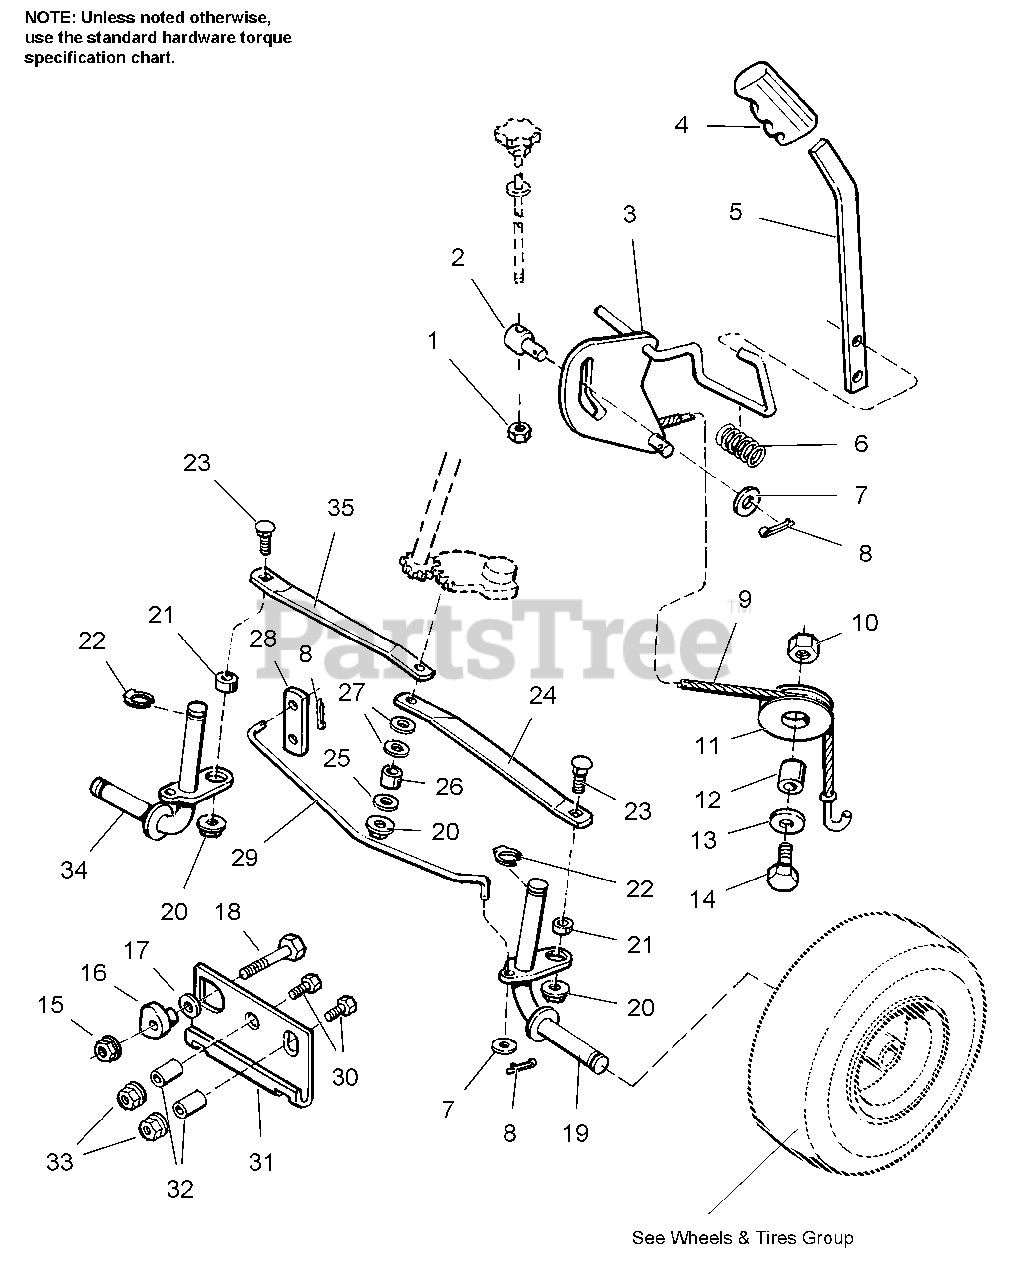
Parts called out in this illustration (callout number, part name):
1	NUT, Hex, 3/8-16
3	ARM ASSY., Lift
4	GRIP, Lever
5	LEVER, Lift
6	SPRING, Compression
7	WASHER, Plain, 13/32 x 7/8 x 5/64
8	COTTER PIN, 3/32 x 3/4
9	CABLE ASSY., Lift
10	NUT, Hex, Esna Lock, 3/8-16
11	PULLEY, Lift
13	WASHER, Plain, 13/32 x 1-1/2 x 1/8
14	CAPSCREW, Hex Hd., 3/8-16 x 1-1/2
15	NUT, Hex, Flange Lock, 3/8-16
17	WASHER, Plain, 13/32 x 7/8 x 1/8
18	CAPSCREW, Hex Hd., 3/8-16 x 1-3/4
19	SPINDLE ASSY., LH
20	NUT, Hex, Flange Lock, 5/16-18
23	CARRIAGE BOLT, 3/8-16 x 1
24	TIE ROD, LH
25	WASHER, Plain, 11/32 x 1 x 1/8
26	SPACER, 21/64 x 1/2 x 5/8
27	WASHER, Plain
30	CAPSCREW, Hex Hd., 1/2-13 x 1-1/2
31	HITCH, Hook
33	NUT, Hex, Flange Lock, 1/2-13
34	SPINDLE ASSY., RH
35	TIE ROD, RH
